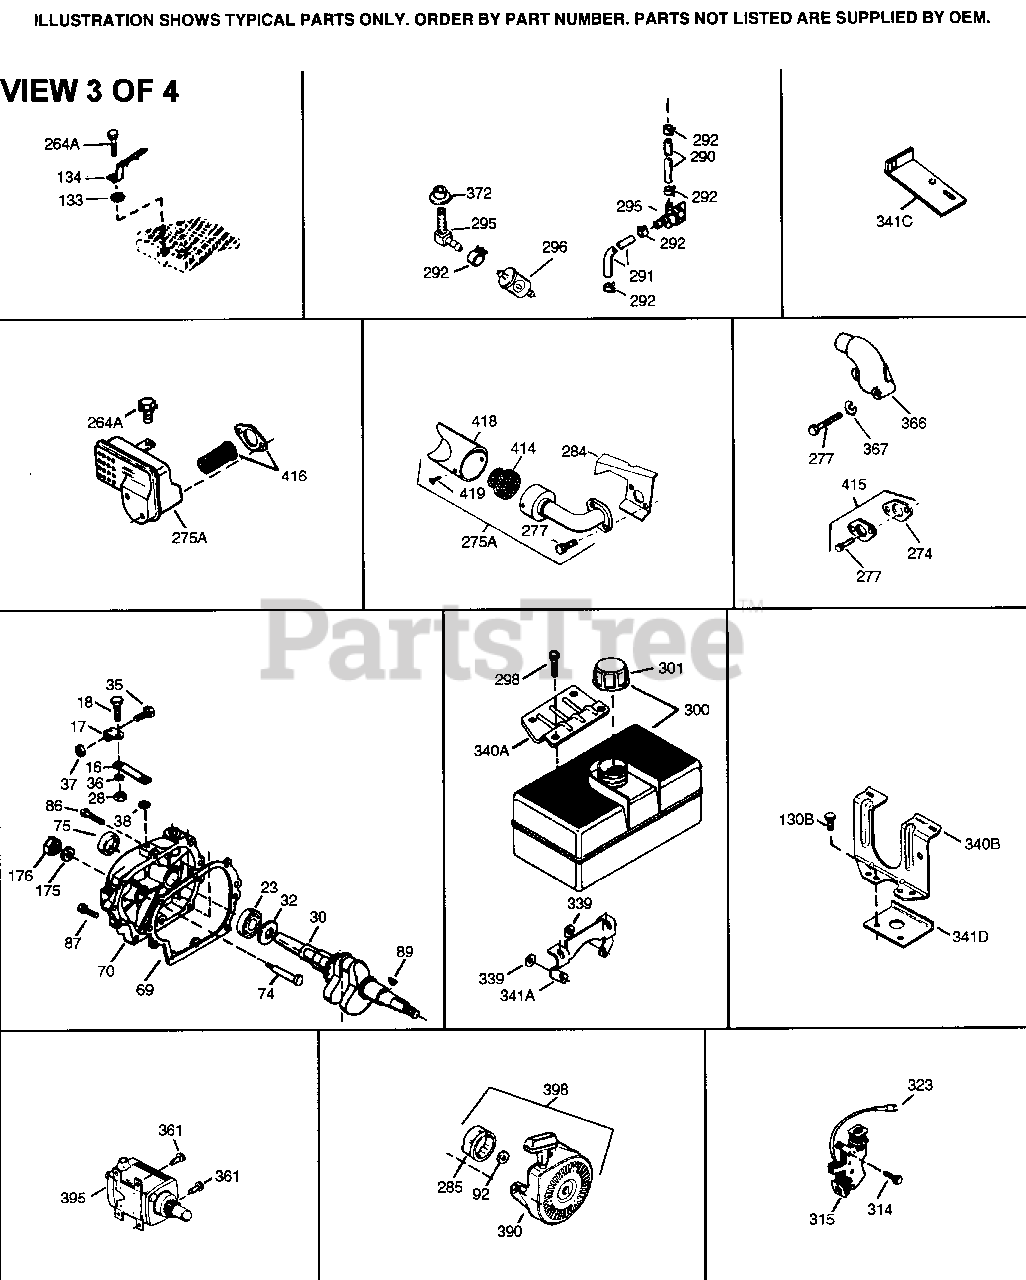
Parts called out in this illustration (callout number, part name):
16	Governor Lever Ass'y. (Incl. 212A)
17	Governor Lever Clamp
18	Screw, Torx T-15, 8-32 x 3/8"
28	Lock Nut, 8-32
30	Crankshaft
35	Screw, 10-32 x 3/4"
36	Lock Washer #8
37	Lock Nut, 10-32
38	Retaining Ring
69	* Cylinder Cover Gasket
70	Cylinder Cover (Incl. 71, 75 & 80))
75	Oil Seal
86	Screw, 1/4-20 x 1-3/16"
87	Screw, 1/4-20 x 1-11/16"
89	Flywheel Key
92	Lock Washer
130B	Screw, 5/16-18 x 5/8"
212A	Bushing
264A	Screw, 1/4-20 x 5/8"
277	Screw, 5/16-18 x 3-3/16
277A	Screw, 5/16-18 x 3-31/32"
280	Heat Shield
285	Starter Cup
290	Fuel Line
292	Fuel Line Clamp
298	Screw, 1/4-15 x 3/4"
300	Fuel Tank (Incl. 292 & 301)
301	Fuel Cap
370K	Starter Decal
390	Rewind Starter (NOTE: This engine co uld have been built with 590704 start er).
416	Spark Arrestor Kit (Optional)
900	Replacement Engine None
900	Replacement Short Block 756318, order from 71-999
